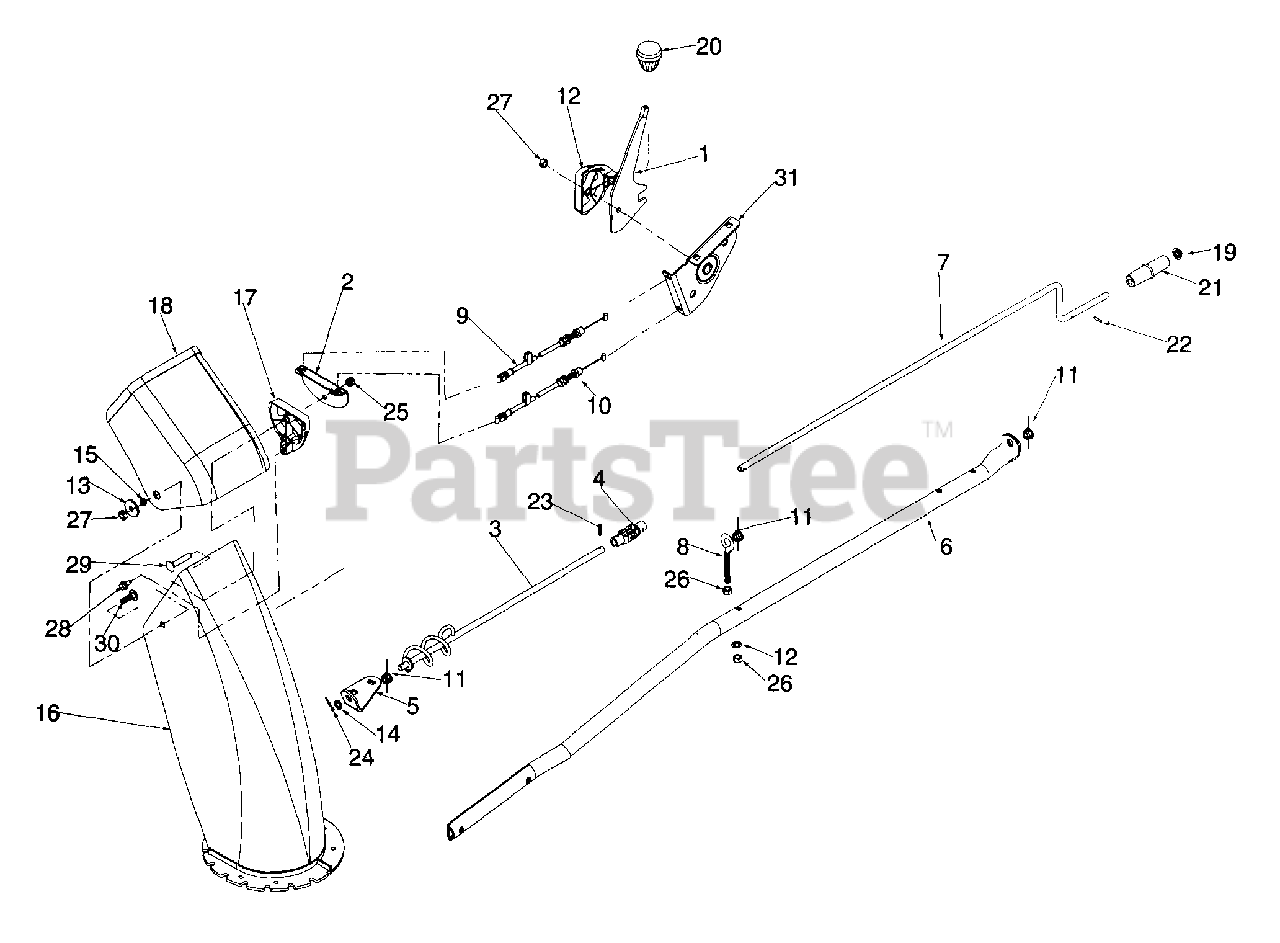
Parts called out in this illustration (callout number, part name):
3	CHUTE CRANK ASSY 18.0 LG - RH
4	BLOCK ASS:JOINT
8	EYE BOLT 5/16-18 X 3.0 LG
9	CBL:CHUTE:W/CULP, 66 LG
10	CBL:CHUTE 66 LG
11	PLASTIC BUSHING .380 ID
12	WASH:BELVL:.340 ID X .872 OD
13	WASH:FL:.344 ID:1.125 OD:.12
14	FL-WASH .385 ID X .62 OD X .06
15	SPCR:CHUT:PIVOT
16	CHUT:LWR:EXTENDED 6" DIA
17	GDE:CBL:CHUTE TILT
18	6" DIA UPPER CHUTE
19	CAP:PUSH X 3/8 ROD
20	KNOB:SHFT:1.60 OD X 1.56
21	KNOB:CRK:1.00 DIA X 3.2 CHUTE
22	PIN:ROLL:1/8 OD:.63
23	SPIROL PIN - 1/8 DIA X .812 LN
24	PIN:COT:3/32 X .750
25	NUT:HX:5/16-18:GRC:LOCK
26	NUT:5/16-18:GRA:HX
27	NUT:LOCK:5/16-18:CEN
28	SCR:1/4-14:.625:HXINDWSH
29	CARRIAGE BOLT 5/16-18 X 1.75
30	SCR:CARR:5/16-18:1.00
